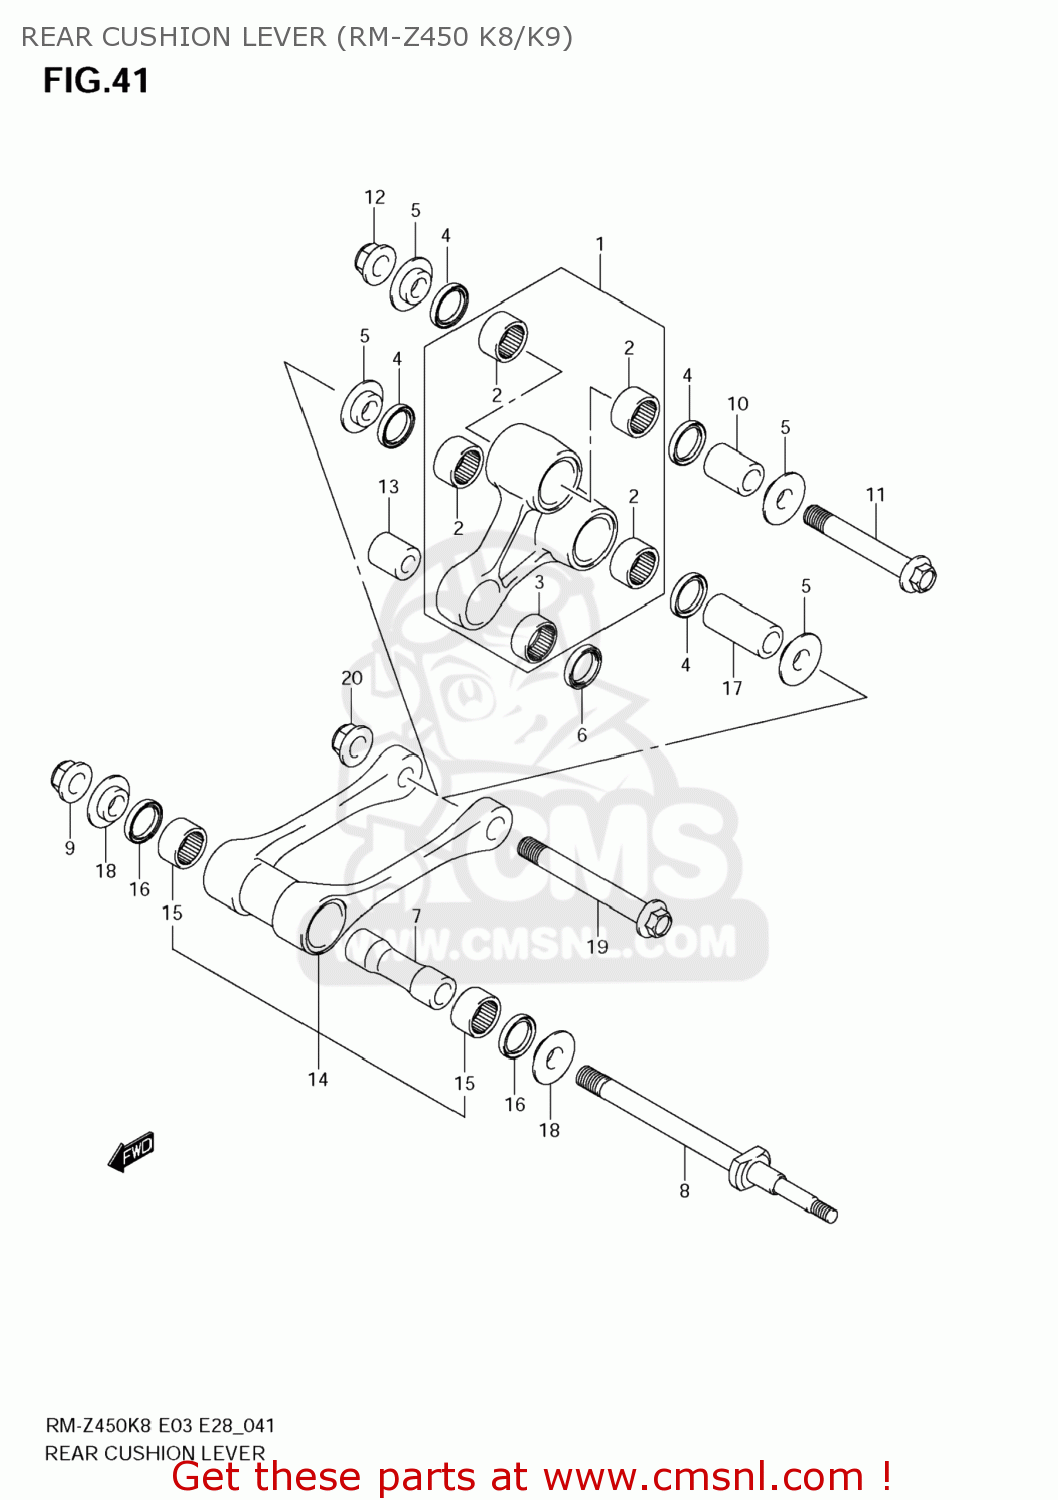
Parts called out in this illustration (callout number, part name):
1	LEVER SET,RR CUSHION
2	BEARING(20X26X14)
3	BEARING(20X26X12)
4	SEAL,OIL(20X26X4)
5	SPACER,RR CUSHION LEVER SIDE
6	SEAL,OIL(20X26X4.5)
7	SPACER,RR CUSHION ROD
8	BOLT,RR CUSHION ROD
9	NUT
10	SPACER,RR CUSHION LEVER UPPER
11	BOLT,RR CUSHION LEVER UPR
12	NUT
13	SPACER,RR CUSHION LEVER RR
14	ROD SET,RR CUSHION LEVER
15	BEARING(20X26X14)
16	SEAL,OIL(20X26X4)
17	SPACER,RR CUSHION LEVER LWR
18	SPACER,RR CUSHION LEVER SIDE
19	BOLT,RR CUSHION LEVER LWR
20	NUT
